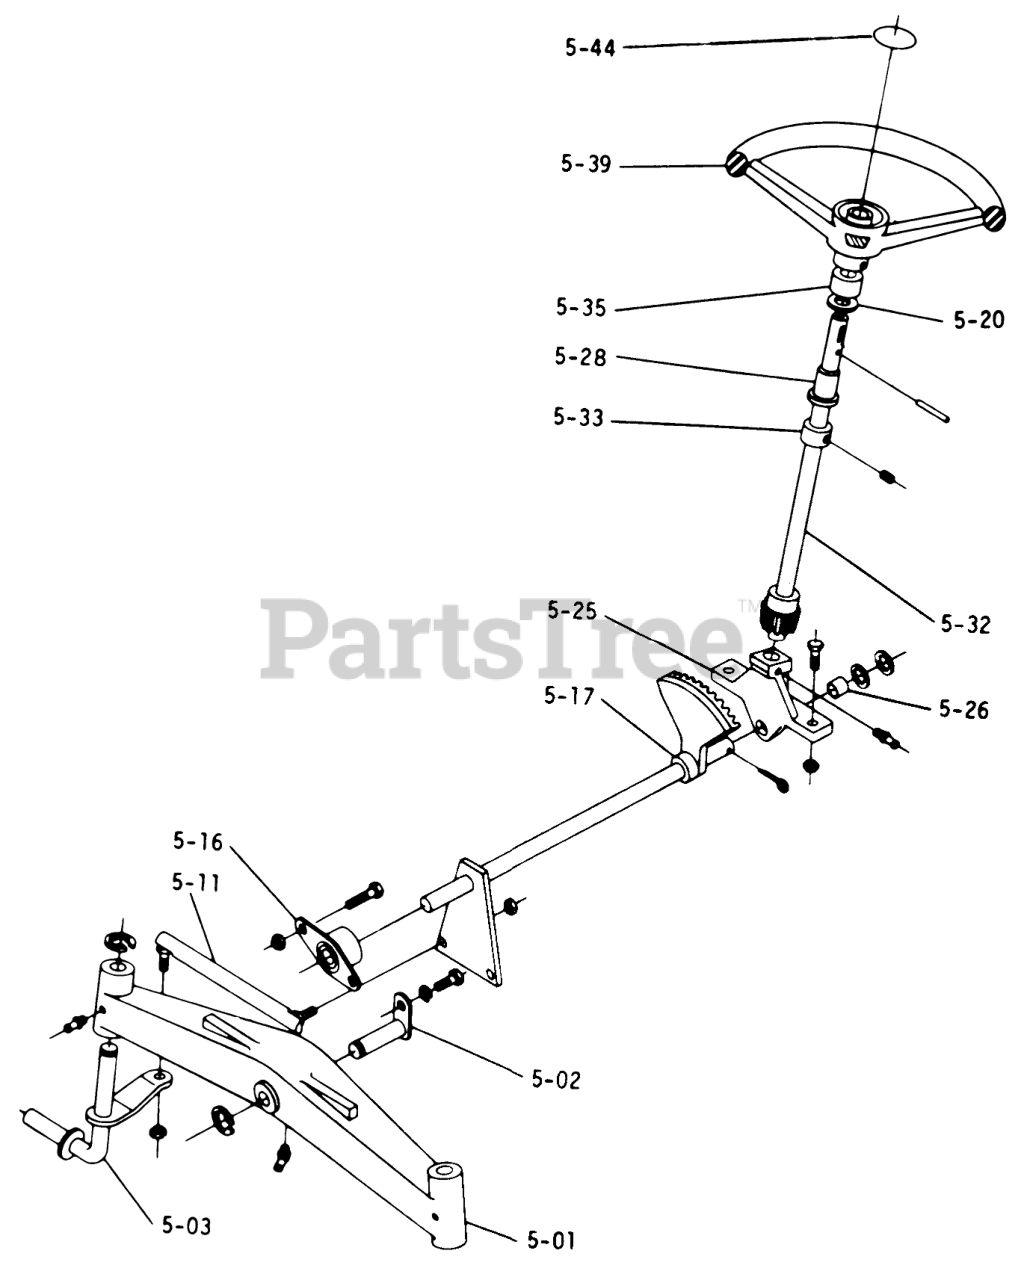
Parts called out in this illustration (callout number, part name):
5-02	PIN AND PLATE ASM
5-16	BEARING-FLANGED
5-20	WASHER-BOWED
5-26	BEARING-BRONZE
5-28	BEARING
